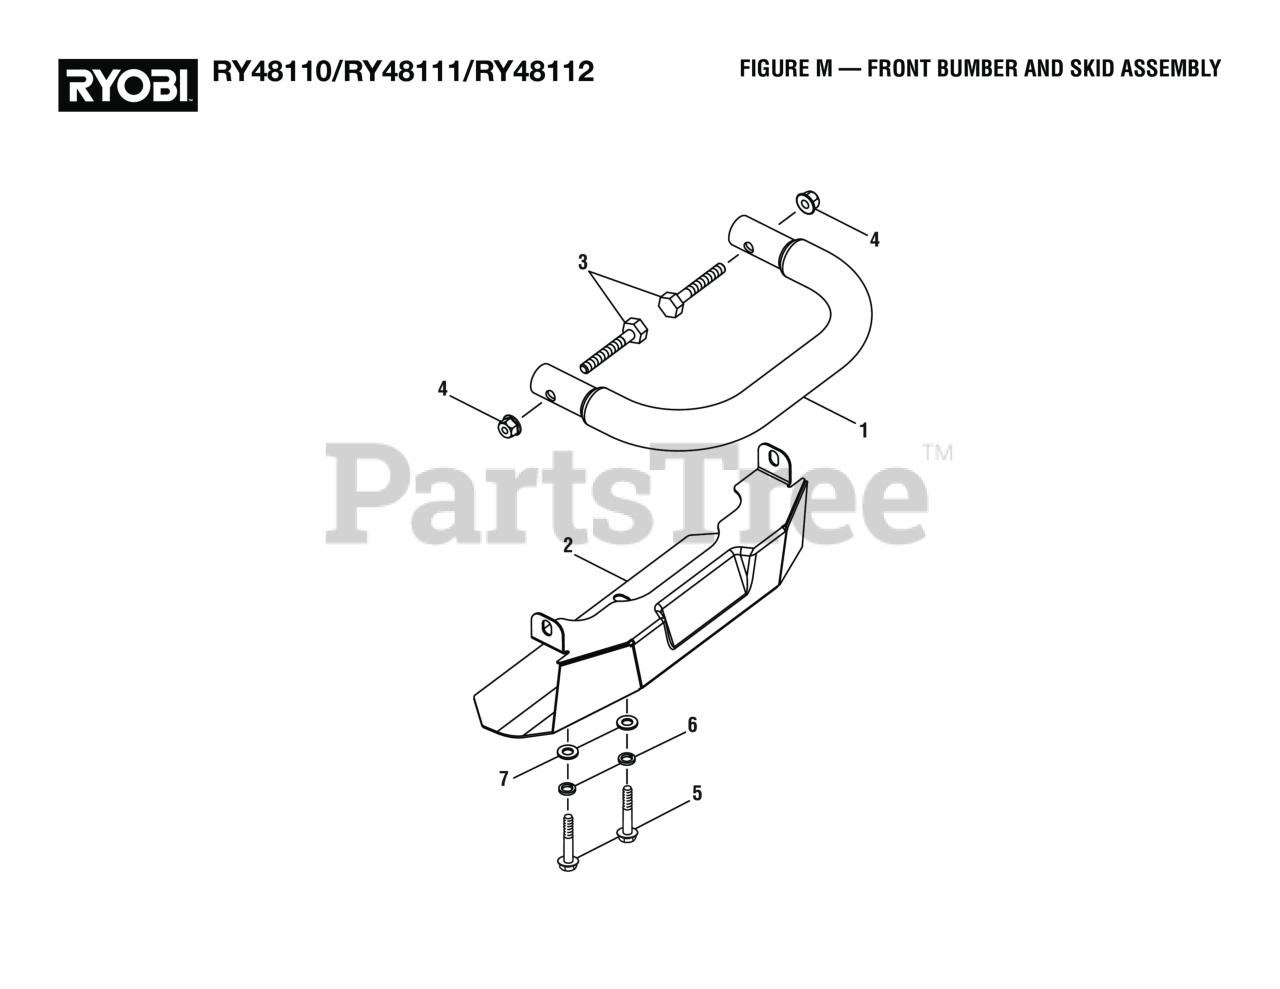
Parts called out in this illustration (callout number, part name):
1	Mower Bumper Tube
2	Front Bumper Cover
3	Shoulder Bolt (M8 x 50 mm)
4	Flange Nut (M8) (For Drive Motor Controller V)
5	Shoulder Bolt (M8 x 45 mm, Hex Flange Hd.)
6	Lock Washer (OD9.8 x ID8.5 x 5t)
7	Washer (OD16 x ID8.4 x 1.6t)
